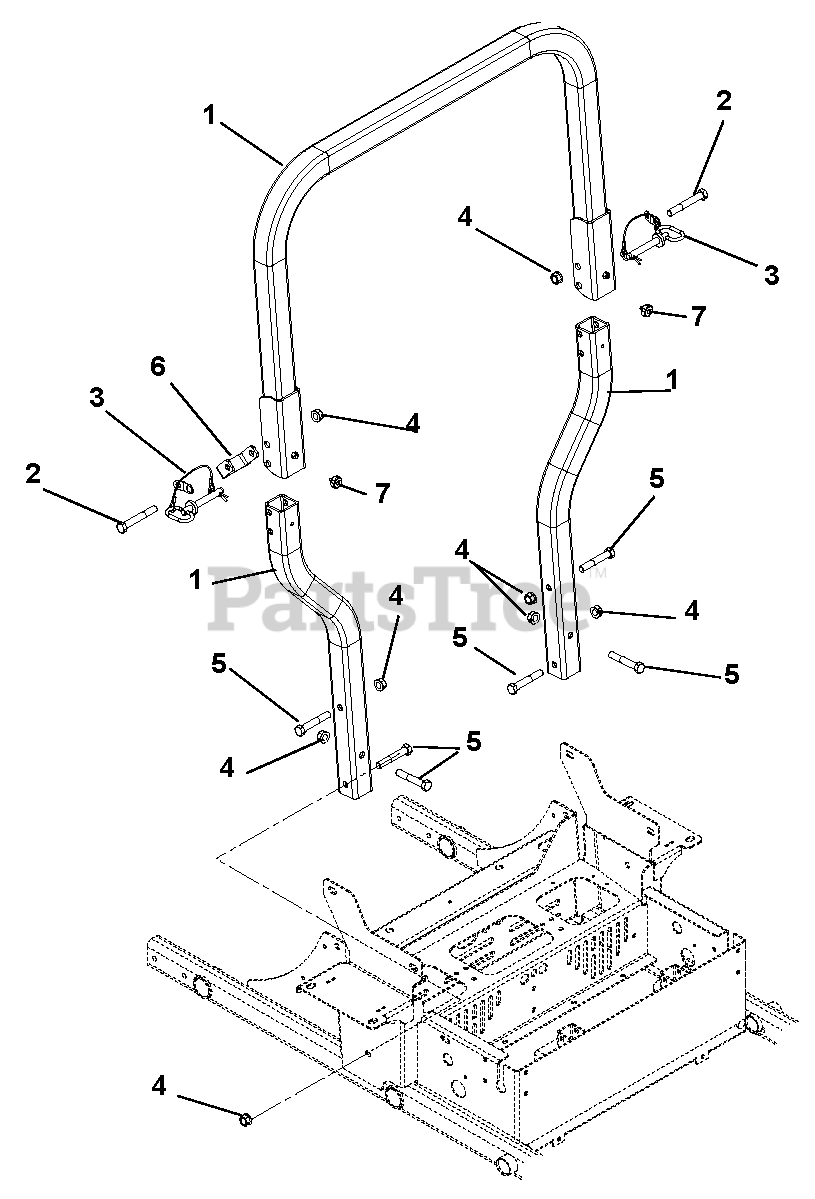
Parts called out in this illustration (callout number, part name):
1	ROPS, PT200 Replacement
2	Bolt, Hex .50-13 x 3.50 Grade 5
3	Assembly, ROPS Pin/Lanyard
4	Nut, Locking-Top-Flange .50-13
5	Bolt, Hex .50-13 x 3.00 Grade 5
6	Bracket, ROPS Stop, Pro-Turn
7	Knob, Round .312-18 x 7.50
